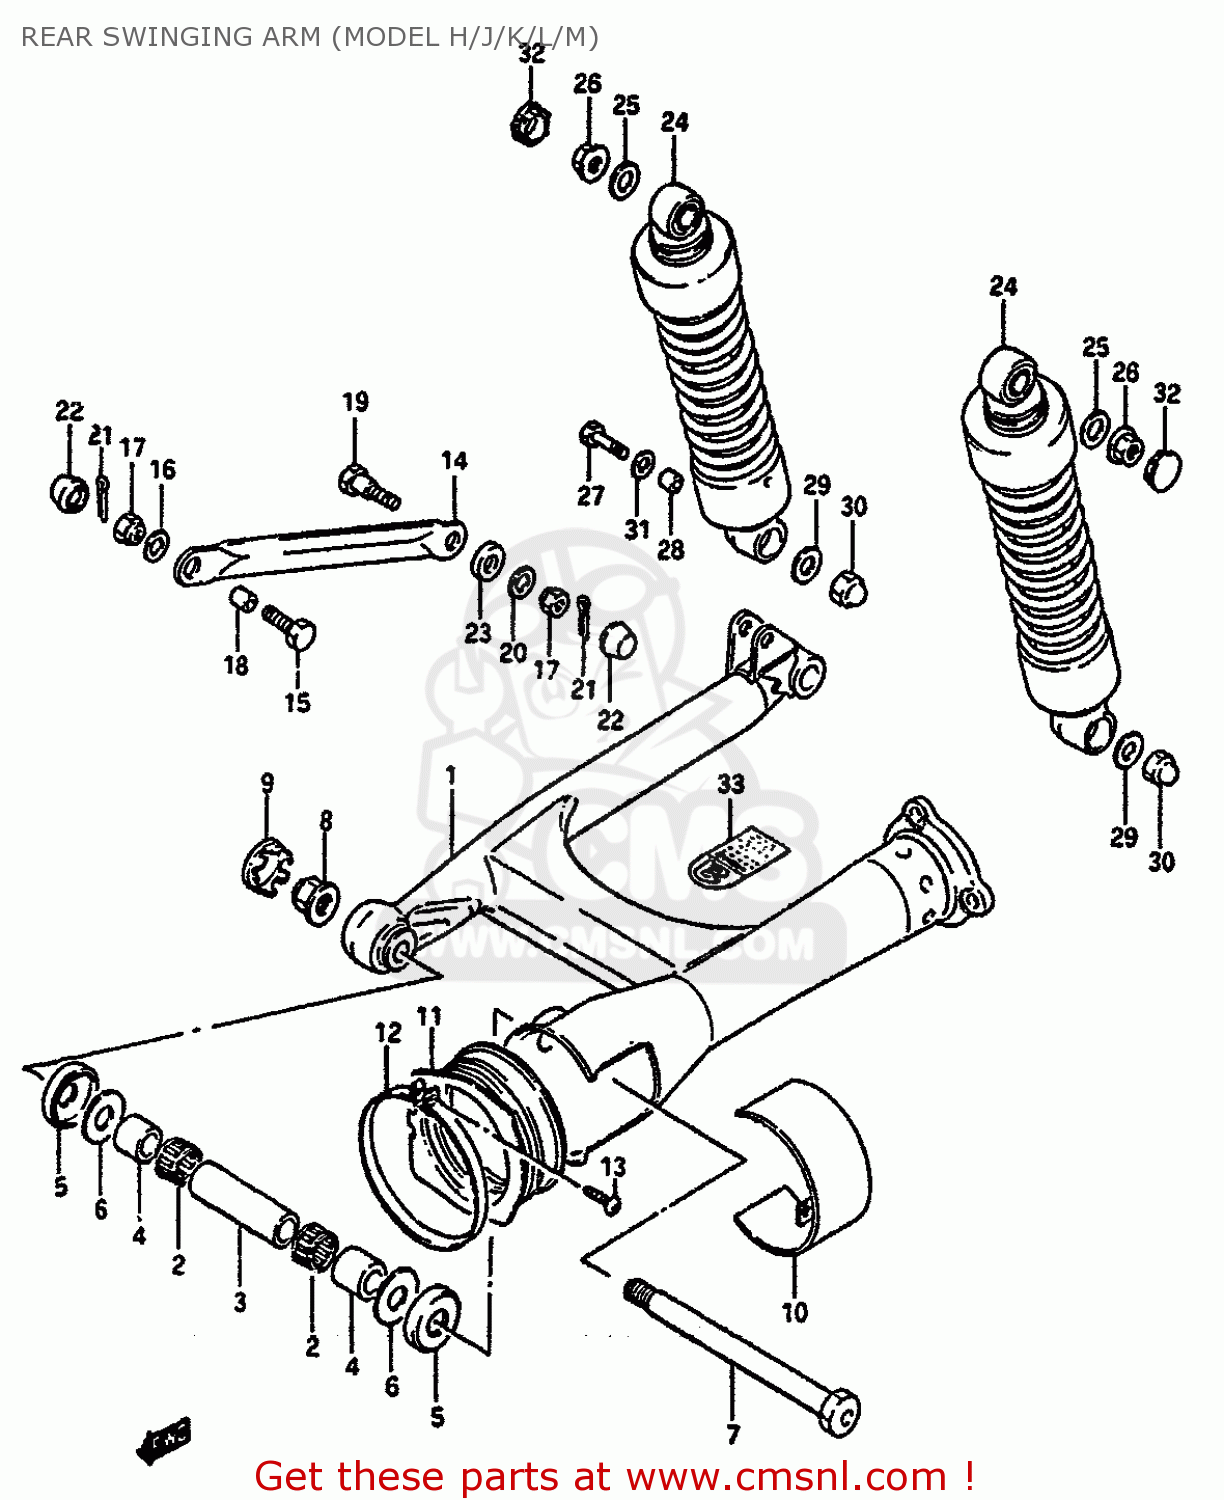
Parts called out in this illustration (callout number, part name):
1	SWING ARM COMP,REAR
2	BEARING(22X29X20)
3	SPACER,REAR SWING ARM PIVOT
4	SPACER,RR SWGARM PIVOT
5	CVR,RR SWGARM DUST SEAL(OD:40)
6	WASHER
7	SHAFT,RR SWINGINGARM PIVOT
8	NUT
9	CAP,RR SWINGING ARM PIVOT,R
10	COVER,REAR SWING ARM PIVOT
11	BOOT,PROPELLER SHAFT
12	CLAMP
13	SCREW 4X25
14	TORQUELINK,RR
15	BOLT(10X28)
16	WASHER
17	NUT
18	SPACER
19	BOLT(10X41)
20	WASHER (10X20X2.3)
21	COTTER PIN
22	CAP
23	CUSHION
24	ABSORBER ASSEMBLY,REAR SHOCK
25	WASHER
26	NUT
27	BOLT(10X39)
28	SPACER (10.2X14X20.7)
29	WASHER
30	NUT
31	WASHER 10MM
32	CAP,FRAME HANDLE GRIP
33	LABEL,ASBESTOS WARNING
